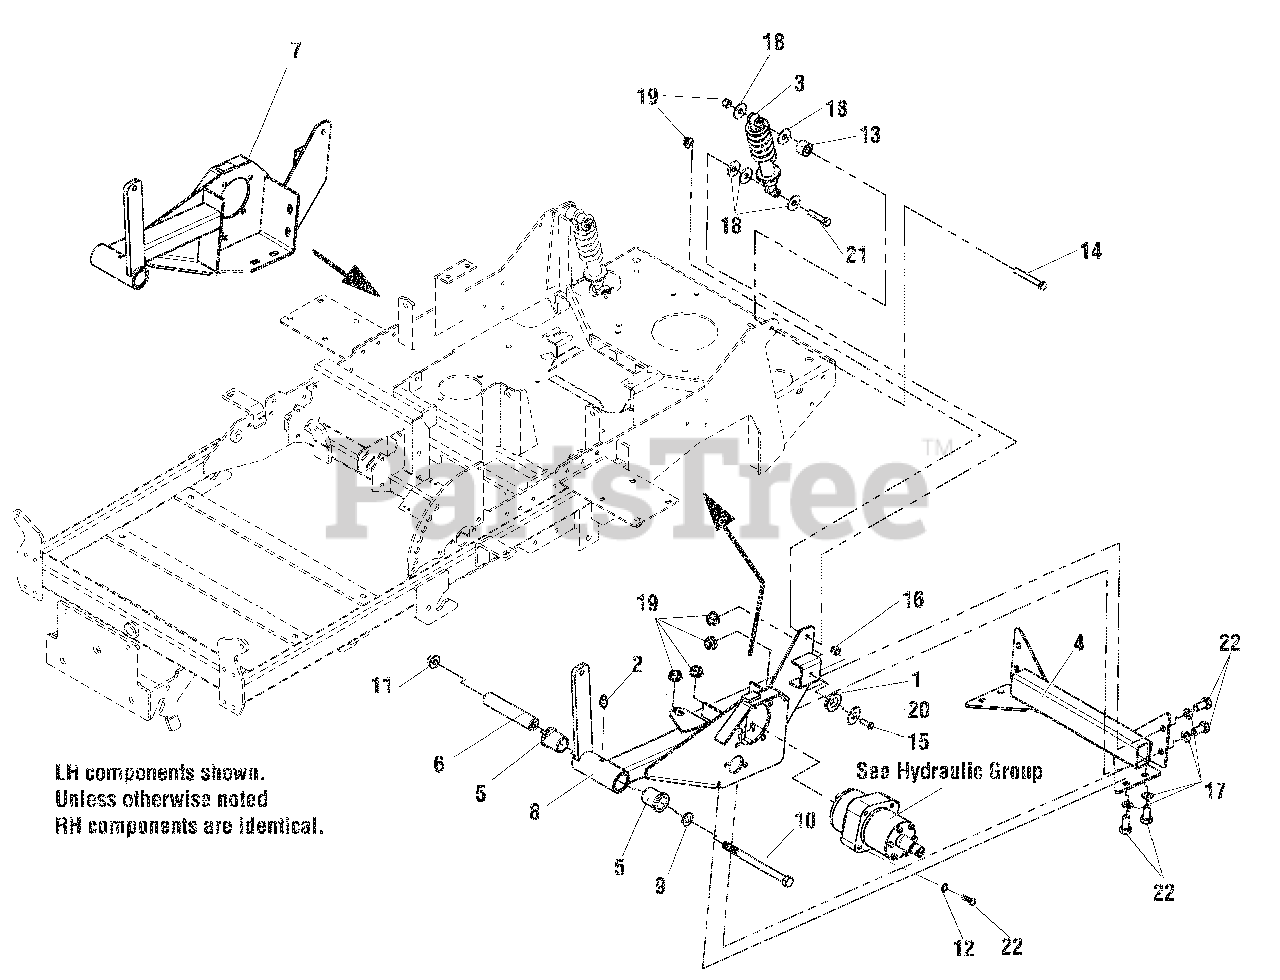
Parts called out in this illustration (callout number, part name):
1	SPACER, .34 X 1.54 X .25 UHMW
2	GREASE FITTING, 1/4-28 STRAIGHT
3	SHOCK, SPRING ASSEMBLY
4	WELD, TIE BAR - RED
5	BUSHING, FLANGE
6	SPACER, .52 X 1.00 X 5.00
7	WELD, TRAILING ARM, RH - RED
8	WELD, TRAILING ARM, LH - RED
9	WASHER, 1/2 SAE
10	BOLT, 1/2-13 X 6-1/2 GD8 YZ
11	NUT, 1/2-13 HEX NYLOCK FLANGE
12	WASHER, 3/8 SPLIT LOCK
13	SPACER, .39 X 1.00X .63
14	BOLT, 3/8-16 X 2-1/2" GD5 CZ
15	SCREW, 5/16-18 X 1 FLAT HD SC
16	NUT, 5/16-18 HEX NYLOCK FLANGE
17	WASHER, 3/8 GD.9 FLAT
18	WASHER, 3/8 FENDER
19	NUT, 3/8-16 HEX NYLOCK FLANGE
20	WASHER, .41 X 1.75 X .14
21	BOLT, 3/8-16 X 1-3/4" GD5 CZ
22	BOLT, 3/8-16 X 1" GD5 CZ
